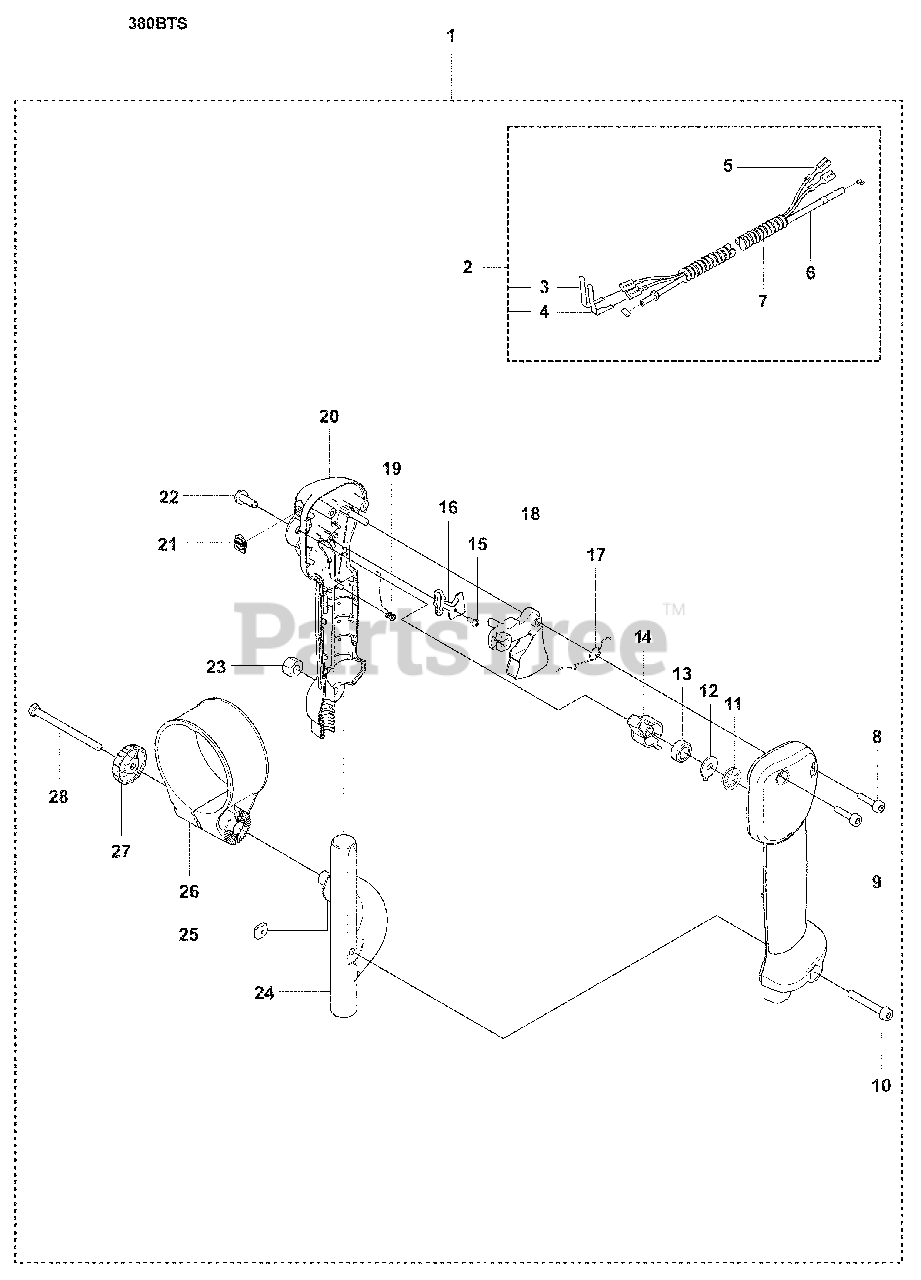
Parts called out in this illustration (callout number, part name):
1	HANDLE ASSY
2	Wiring Assembly, 380BTS
3	Contact Spring
4	Contact Spring
9	Right Half Handle
10	Screw, Ihscfm M5 X 35 10.9 ZP
13	Spring, Rubber
14	Stop Lever
20	Left Half Handle
22	Pivot Shaft
25	Square Nut
26	HOLDER TH
27	Air Filter Cover Knob
